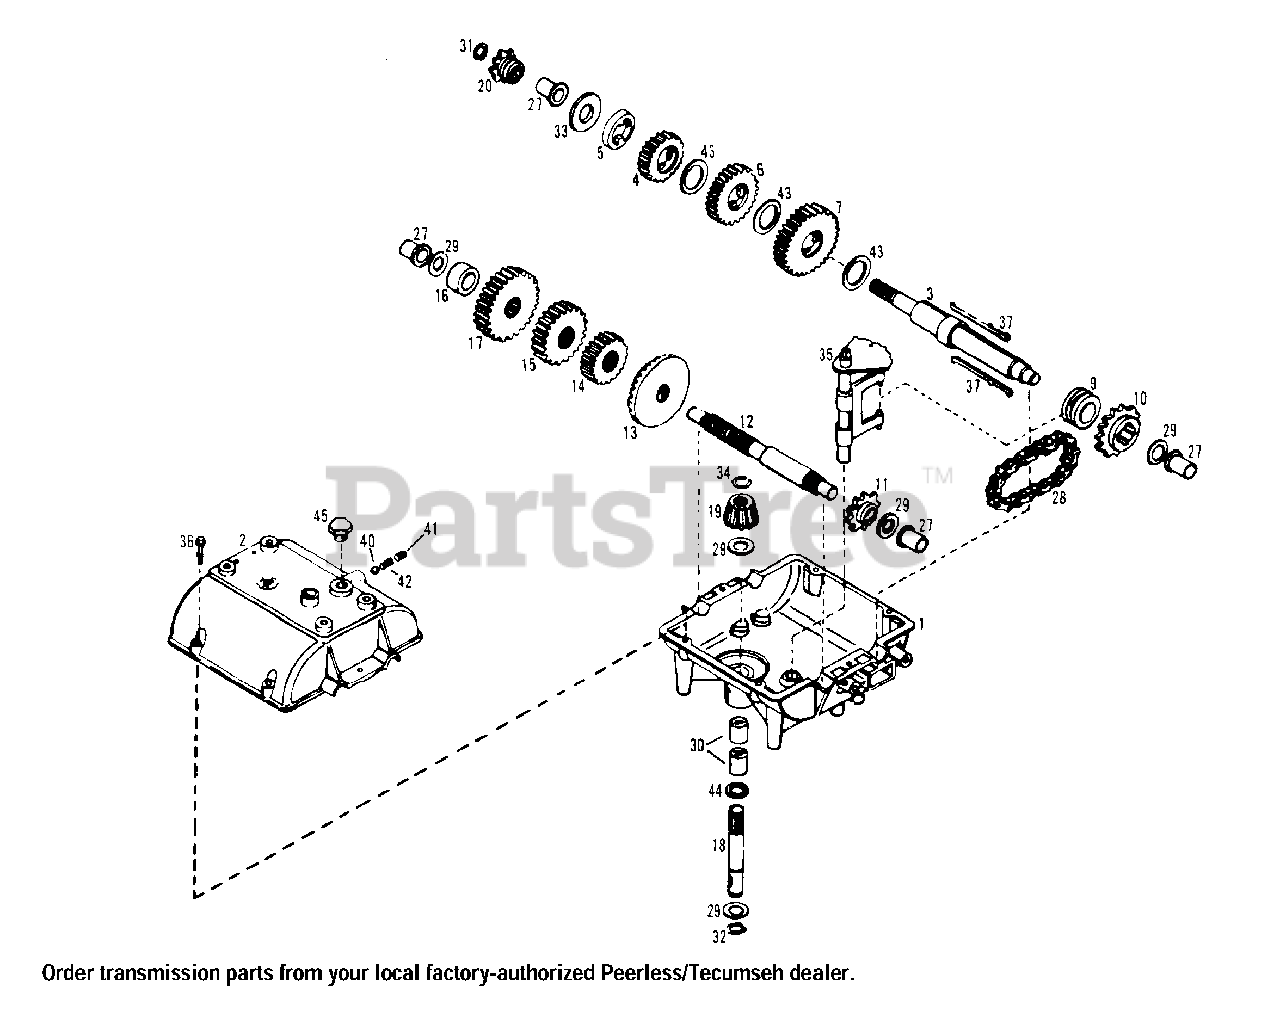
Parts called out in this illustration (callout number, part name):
1	Case, Transmission
2	Cover, Transmission
3	Output Shaft
4	Spur Gear (20 Teeth)
5	Spacer, Keyed
6	Spur Gear (30 Teeth)
7	Spur Gear (35 Teeth)
9	Shift Collar
10	Sprocket (14 Teeth)
11	Sprocket (10 Teeth)
12	Countershaft
13	Bevel Gear (42 Teeth)
14	Spur Gear (15 Teeth)
15	Spur Gear (20 Teeth)
17	Spur Gear (30 Teeth)
18	Input Shaft
19	Bevel Pinion, Input
20	Sprocket (8 Teeth)
27	Bushing, Flanged
28	Chain, Roller (No. 41 Chain, 22 Links)
29	Thrust Washer
30	Needle Bearing
31	Retaining Ring
32	Retaining Ring
34	Retaining Ring
35	Rod & Fork Assembly, Shift
36	Hex Flange Screw, Thread-Forming, 1/4-20 x 1-1/4
40	Ball, Steel, 5/16"
41	Setscrew, 3/8-16 x 3/8
42	Spring
43	Thrust Washer
44	"O" Ring
